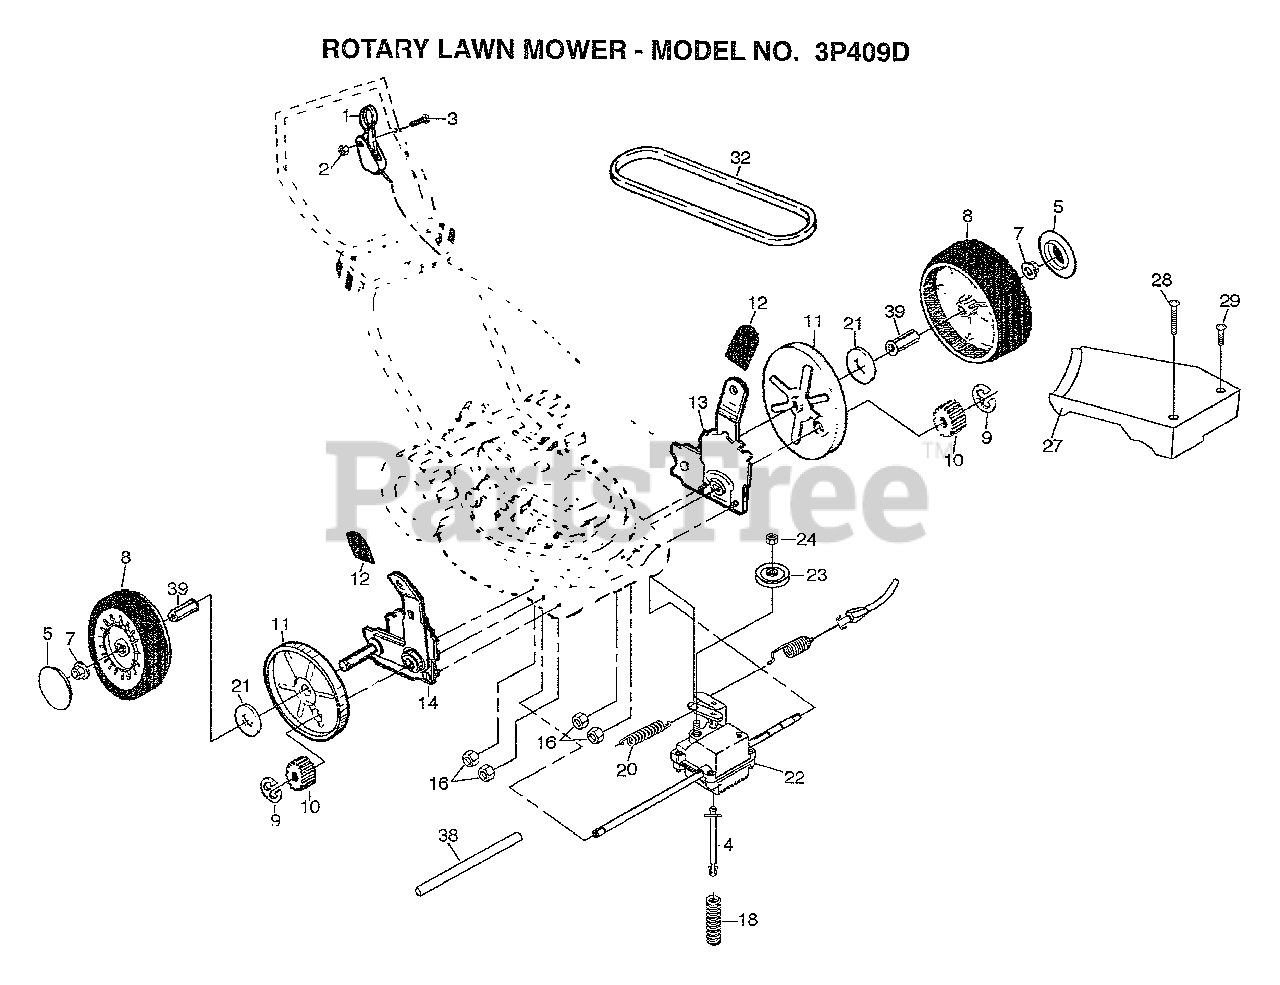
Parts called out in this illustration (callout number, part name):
1	CONTROL.DRV.56.25
2	LOCKNUT
3	PAN HEAD SCREW
4	SPRING.RETAINER.
5	HUB CAP
7	NUT.HXFLG.LOCK.
8	WHEEL.8X2.LP.PR
9	E-RING.7/16.RE.
10	PINION.GEAR
11	DUST SHROUD PM
12	KNOB PM
13	WHEEL.ADJ.ASM.LH.
14	WHEEL.ADJ.ASM.RH.
18	SPRING.TENSION
20	SPRING
21	WASHER FLUT
23	PULLEY.DRIVEN
24	LOCKNUT
27	COVER DRIVE BLK
28	SCREWL.SLOT.TORXT
29	SCREW.SLOT.TORTX.
38	DRV SHAFT TUBE PM
39	BUSHING.HEX
